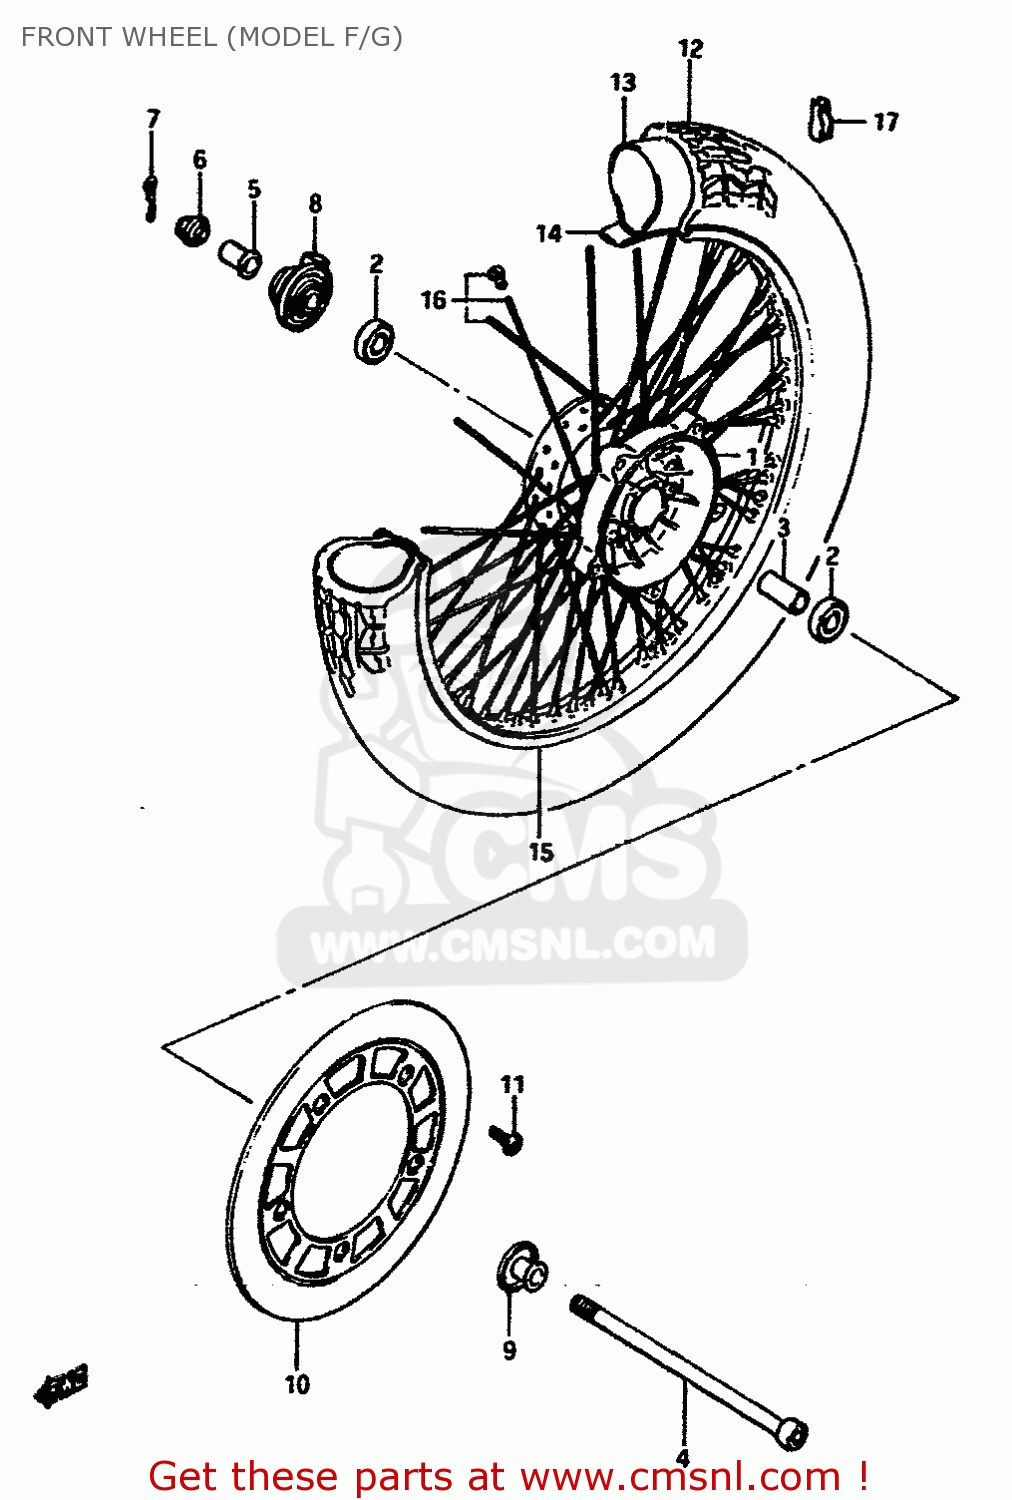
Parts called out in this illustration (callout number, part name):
1	HUB ASSEMBLY,FRONT
2	BEARING
3	SPACER(15.3X21.7X65)
4	AXLE,FRONT
5	SPACER,FRONT AXLE,RIGHT
6	NUT
7	PIN,FRONT AXLE
8	BOX ASSY,SPEEDOMETER GEAR
9	SPACER COMP,FRONT AXLE
10	DISC,FR BRAKE
11	BOLT(8X25.5)
12	TIRE,FRONT
13	TUBE,INNER
14	PROTECTOR,WHL INR TUBE
15	RIM,FRONT WHEEL (MT2.15)
16	SPOKE SET,FR WHEEL
17	BALANCER,WHEEL
